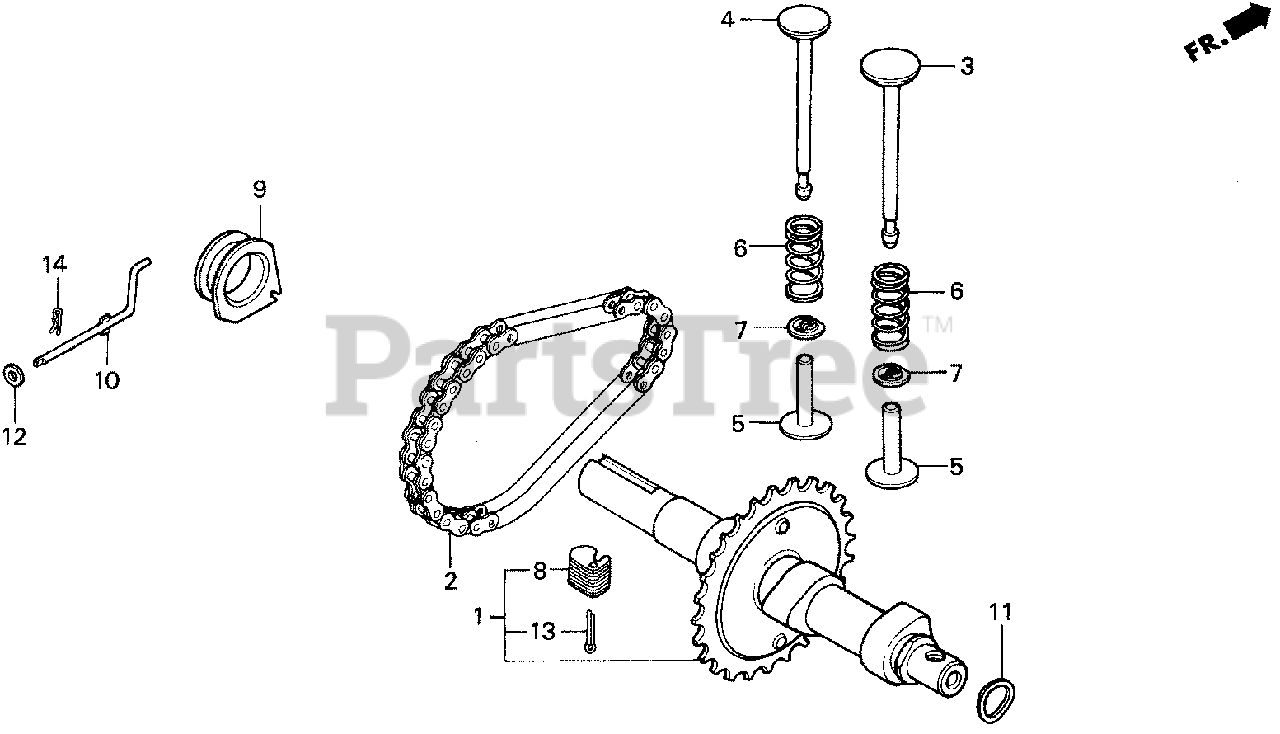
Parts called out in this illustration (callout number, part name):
1	CAMSHAFT ASSY.
2	CHAIN, CAM
3	VALVE, IN.
4	VALVE, EX.
5	LIFTER, VALVE (39.6MM)
5	LIFTER, VALVE (39.9MM)
6	SPRING, VALVE
7	RETAINER, VALVE SPRING
8	WEIGHT, GOVERNOR
9	SLIDER, GOVERNOR
10	SHAFT, GOVERNOR ARM
11	WASHER, THRUST SPRING
12	WASHER, PLAIN (5MM)
13	PIN, COTTER (3.0X45)
14	PIN, LOCK (8MM)
